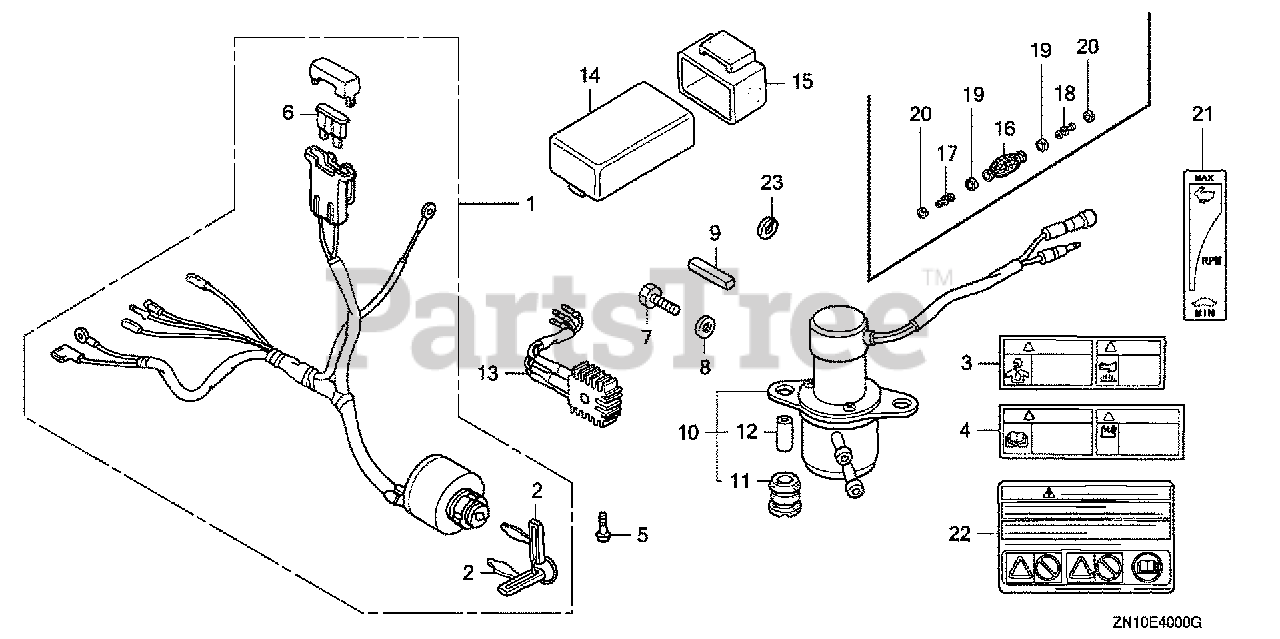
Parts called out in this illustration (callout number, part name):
13	RECTIFIER ASSY.
14	CONTROL UNIT, VALVE
15	CUSHION, VALVE CONTROL UNIT
